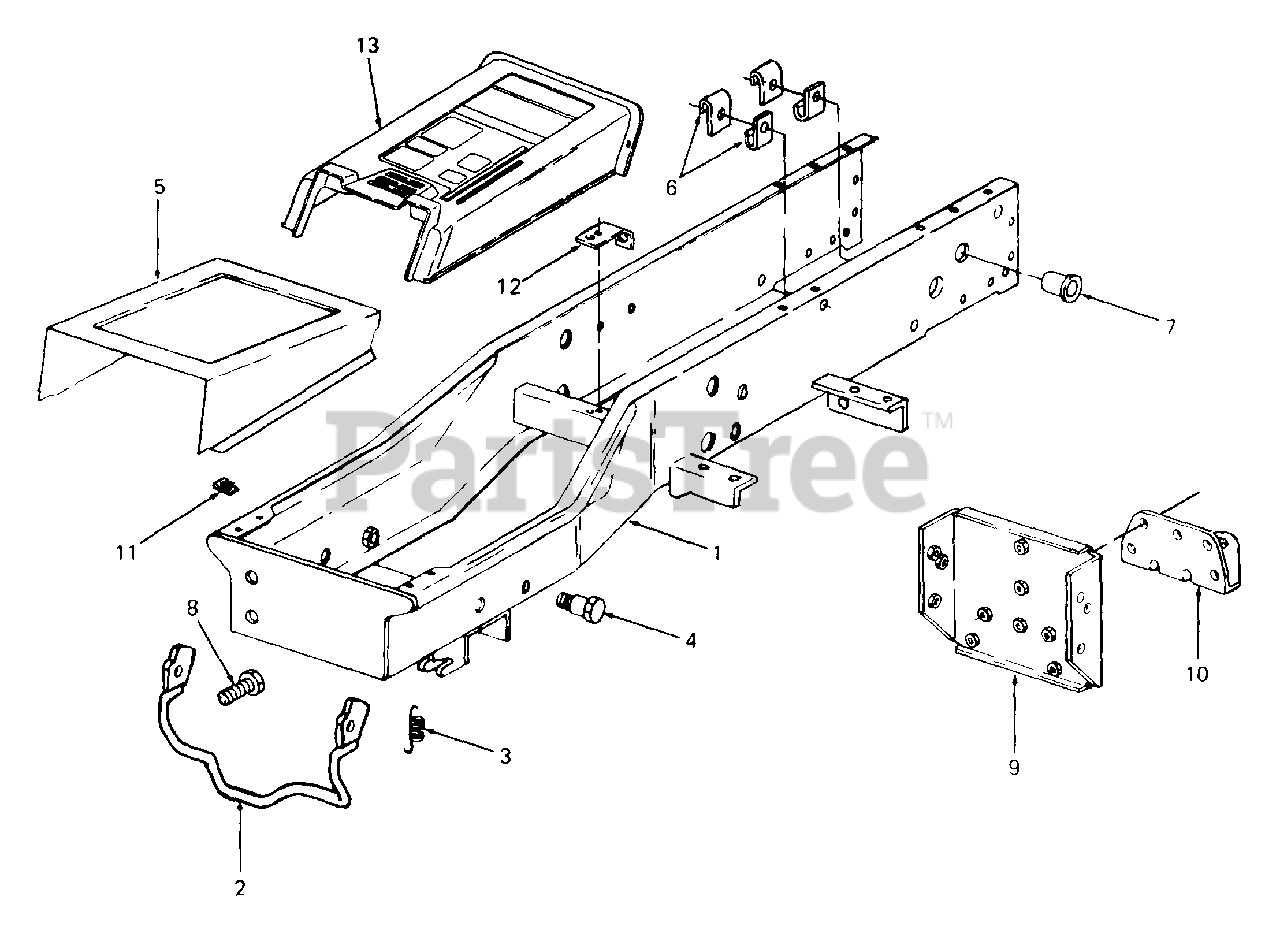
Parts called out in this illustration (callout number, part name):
3	Spring, Latch
4	Bolt, Shoulder
6	Clip, Cable
7	Bushing, Snap
8	Screw, Adjustment, 1/2-20 X 1.0 Lg GR5
11	Nut, Speed
12	Bracket, Switch
13	Cover Frame
